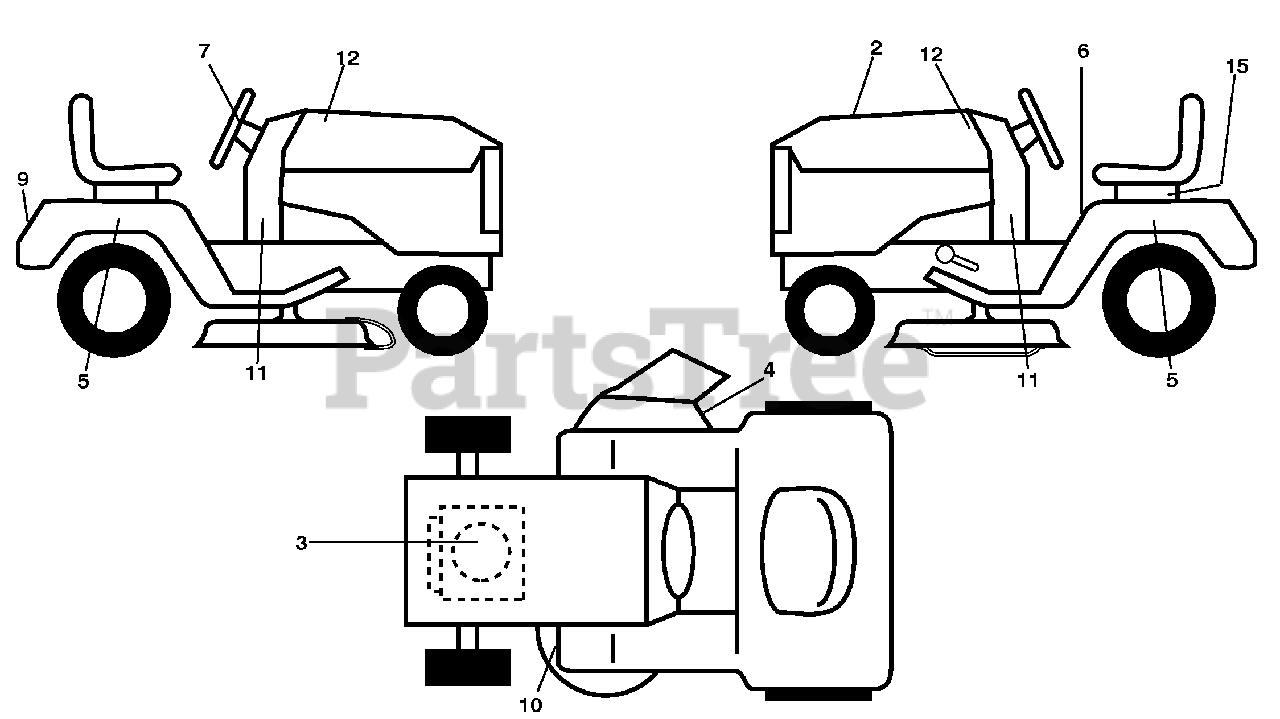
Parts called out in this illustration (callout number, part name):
2	Decal, Replacement
3	Decal, Engine HP
4	Decal, Warning
5	Decal, Fender
6	Decal, Fender Warning (E&F)
7	Decal, Ins Str Wh
9	Decal, Fender
10	Decal, V-Belt Sch.
11	Decal, Lower Dash
12	Decal, Hood RH/LH
15	Decal, Caution, Battery
15	Pad Footrest RH
15	Pad Footrest LH
15	Decal, Handle Lft Height Adj.
15	Manual, Operator's, English & French
15	Manual, Operator's, Spanish
15	Manual, Parts, English & French
